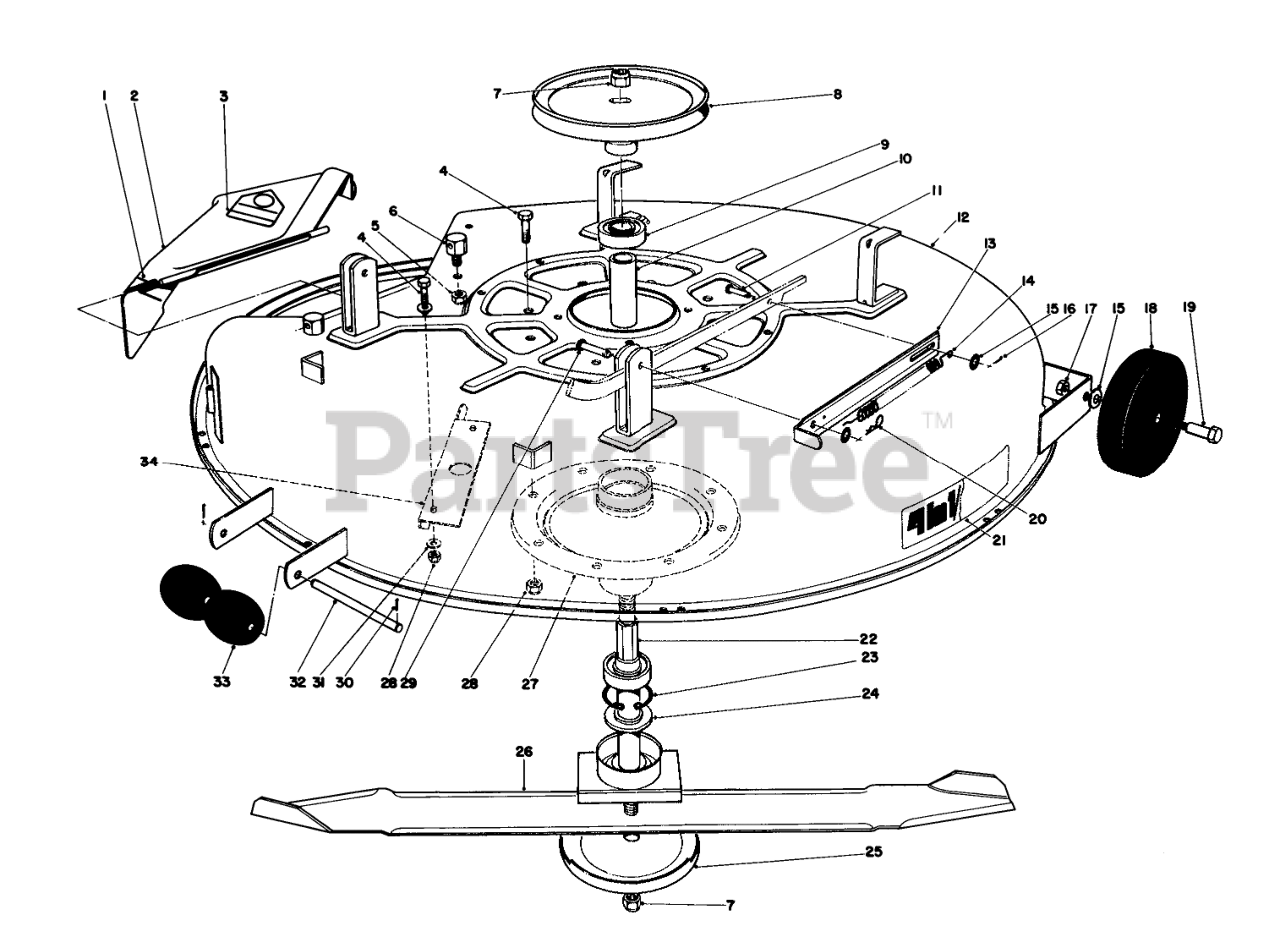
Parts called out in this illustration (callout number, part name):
1	SPRING
2	Deflector Assembly (Incl. Ref. #3)
3	DECAL-DANGER
4	SCREW-HH
5	NUT-LOCK, SIDE
6	POST-PIVOT
8	PULLEY(BLADE DRIVE)
9	BEARING-BALL
10	Spacer-Bearing
11	PIN-CLEVIS
13	DECK SPRING STRAP R
14	DECK TENSION SPRNG O
15	WASHER-FLAT
16	PIN-COTTER
17	Nut
18	DECK WHEEL
20	PIN-COTTER
21	DECK DECAL
22	SPINDLE SHAFT WA
23	RING-RETAINING
24	SPACER-SPINDLE
25	Cup
26	Blade
27	Spindle Body
28	NUT-LOCK, NI
29	PIN-CLEVIS
30	PIN-COTTER
31	WASHER-PLAIN
32	ROLLER SHAFT
33	ROLLER
34	Baffle Deck
